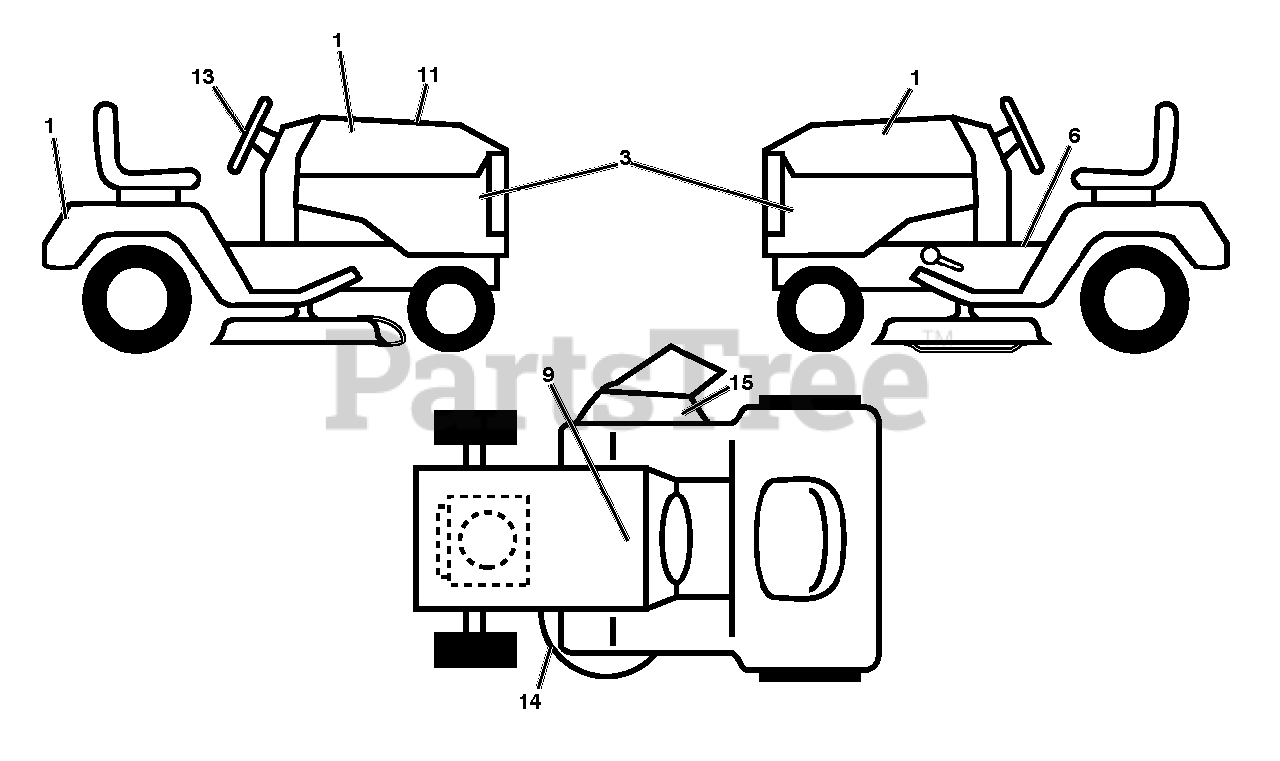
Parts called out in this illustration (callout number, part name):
9	DECAL BTRY SYMBOLS
11	DECAL.RPL.
14	DECAL V BELT SCHEMATIC
15	DECAL
